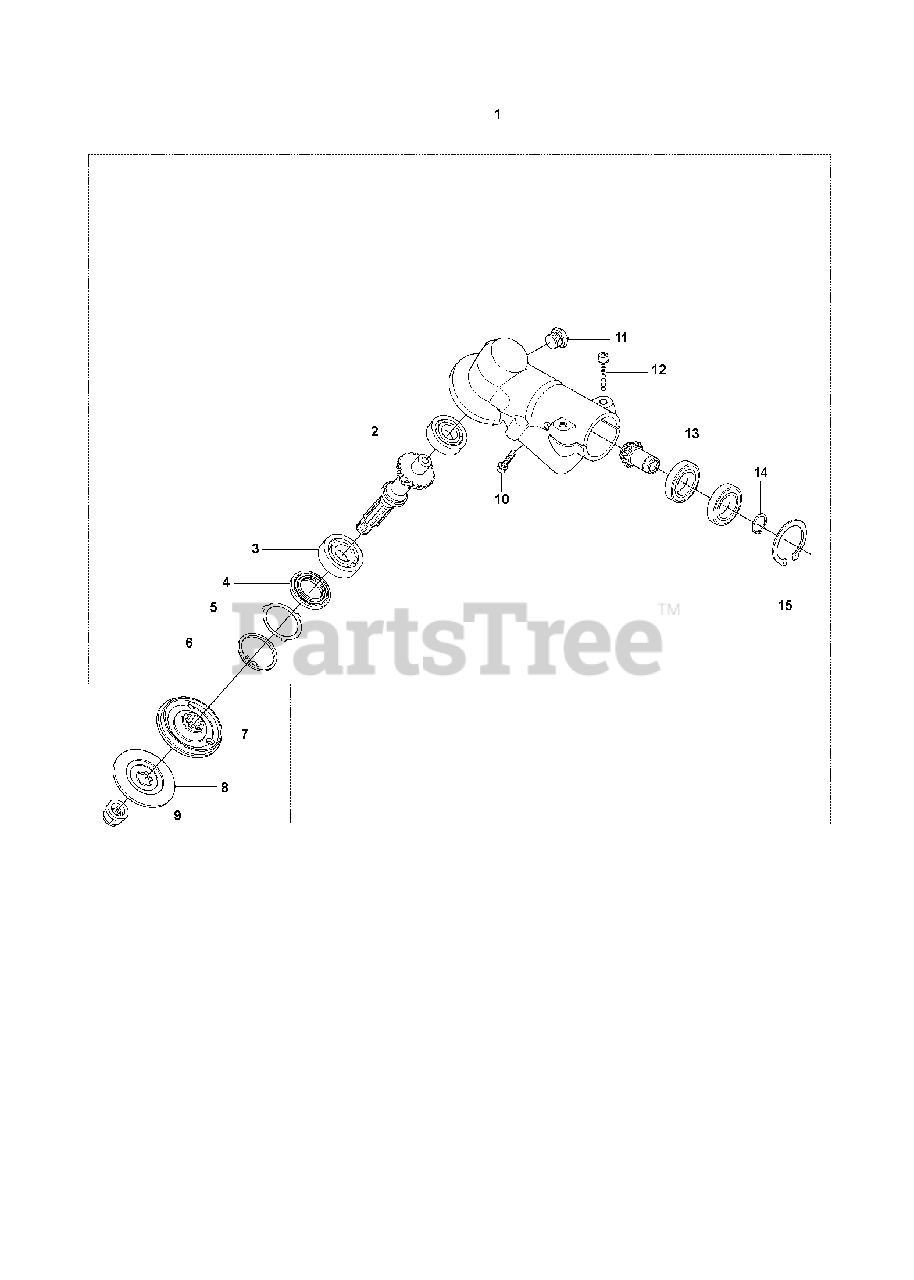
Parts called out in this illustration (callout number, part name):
1	GEAR ASSY
2	BALL BEARING
3	BALL BEARING
4	SEAL
5	WASHER
6	RETAINING RING SGH 35
8	SUPPORT FLANGE
9	NUT BLADE
10	SCREW
11	PLUG
12	SCREW
13	BALL BEARING
14	RETAINING RING SGA 15
15	RETAINING RING
